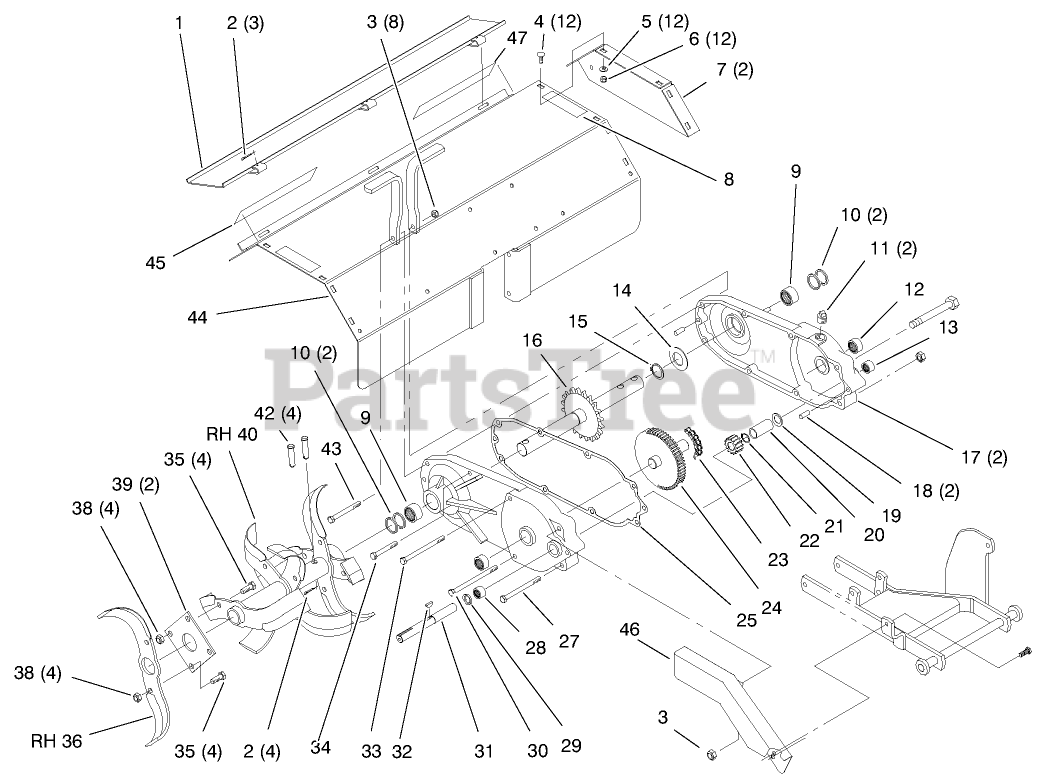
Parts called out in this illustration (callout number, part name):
1	GUARD ASM
2	PIN-COTTER
3	NUT-LOCK, NI
4	BOLT-CARR
5	WASHER-PLAIN
6	NUT-LOCK, NI
7	COVER-TINE END
8	DECAL-DANGER
9	BEARING-NEEDLE
11	PLUG-PIPE, SQH
12	BEARING-NEEDLE
13	BEARING-NEEDLE
14	WASHER
15	RING-RETAINING
16	TINE SHAFT ASM
18	PIN-ROLL
19	WASHER-THRUST
20	TUBE-SPACER
21	RING-SNAP
23	CHAIN
26	SCREW-HH
27	SCREW-HH
28	BEARING-NEEDLE
29	SEAL-OIL
30	SCREW-HH
31	SHAFT-INPUT
32	KEY-WOODRUFF
34	SCREW-HH
35	SCREW-HH
37	Tine-LH
38	NUT-LOCK, NI
40	RH TINE ASM
41	LH TINE ASM
42	PIN-CLEVIS
43	SCREW-HH
46	GUARD - TILLER
